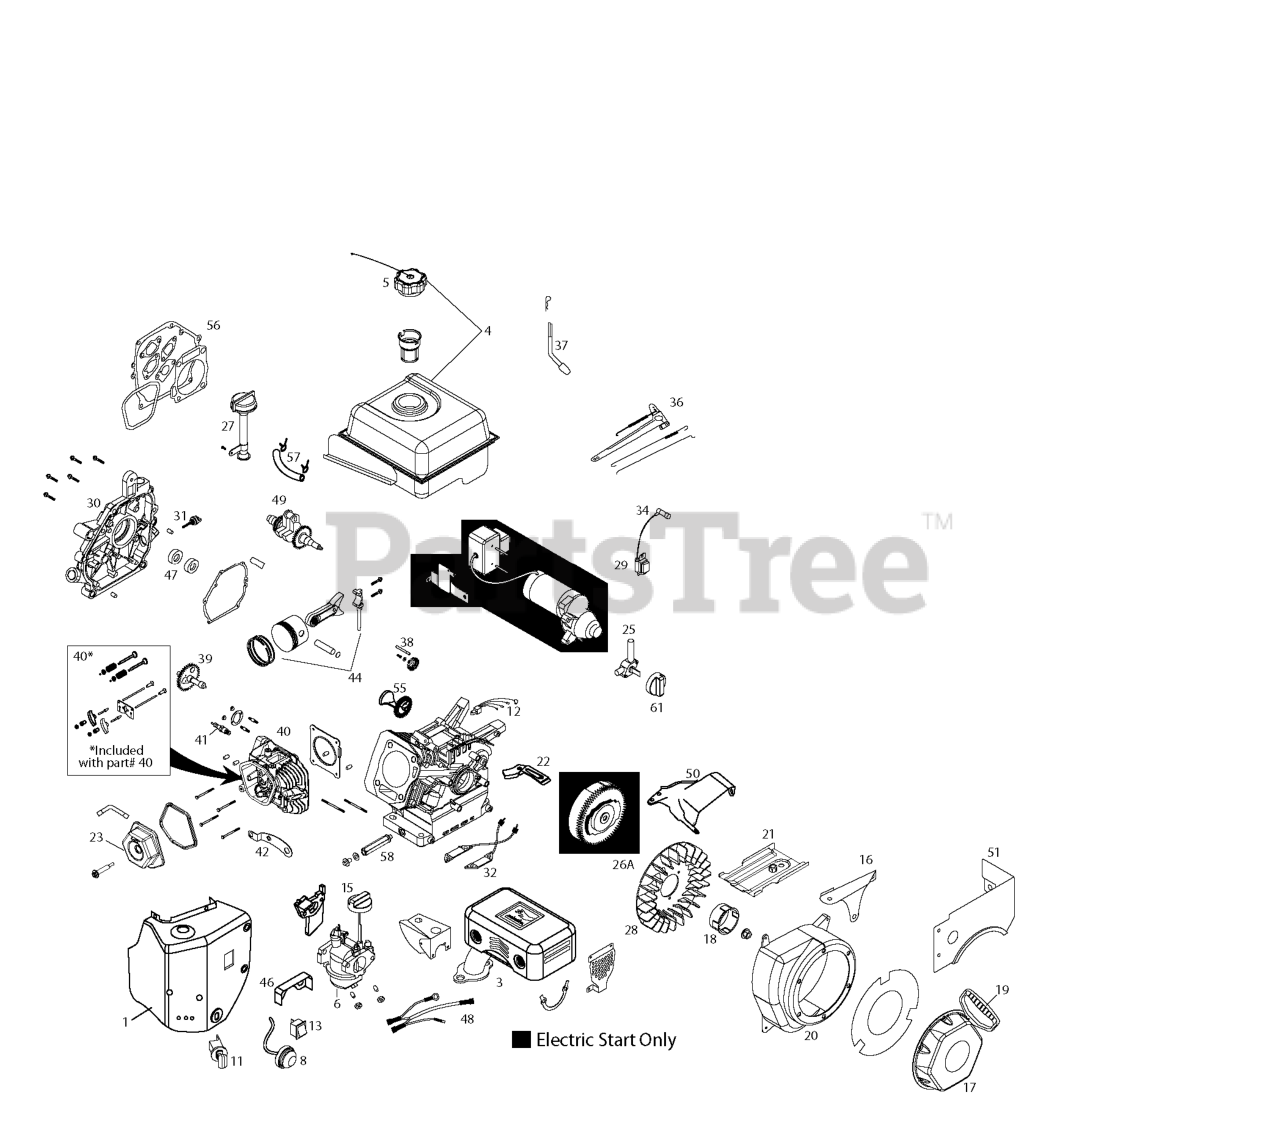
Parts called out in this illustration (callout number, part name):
1	HEATER.BOX.ASSY-SNW(SKSN4100)
3	MUFFLER.ASSY.SNOW(SKSN4200)
4	FUEL.TANK.ASSY.SNOW(SKSN4300)
5	FUEL.TANK.CAP.SNOW(SKSN4301)
6	CARBURETOR.ASSY.SNOW(SKSN4302)
8	PRIMER.BULB.ASSY(SKSN4304)
10	ELEC.START.ASSY.SNOW(SKSN4400)
11	KEY.SWITCH.ASSY.SNOW(SKSN4401)
12	CDI.BOX.ASSY.SNOW(SKSN4404)
13	ON/OFF.SWITCH.SNOW(SKSN4403)
15	CHOKE.KNOW.SNOW(SKSN4500)
16	CHUTE.LOWER.BAGGER.30"(2 2 BR)
17	RECOIL.START.ASSY.SNW(SKSN4600
18	STARTER.CUP.SML.SNOW(SKSN4601)
19	STARTER.GRIP.SNOW(SKSN4603.1)
20	BLOWER.HSG.ASSY.ELEC(SKSN4602
21	SHIELD.CYLINDER.SNOW(SK4141010
22	SHIELD.U/FYWHL.CHARG(SKSN4604)
23	VALVE.COVER.LCT.414CC.
25	FUEL.PETCOCK.SNOW(SKSN4900)
26	FLYWHEEL.ASSY.ELEC.START
26A	FLYWHEEL.ASSY.MAN.START
27	HIGHOIL.FILL.ASSY.KIT(SKSN4911
28	FLYWHEEL.FAN(SK4144000)
29	IGNITION.COIL.ASSY
30	CRANKCASE.CVR.ASSY(SK4143600)
31	NONREMVABLE.OIL.PLUG(SK4143715
32	CHARGING.COIL.AC/DC(SK4141710)
33	ELECTRIC.START.BRKT(SKSN4405)
34	SPARK.PLUG.BOOT
36	GOVERNOR.ARM.ASSY(SKSN4502)
37	GOVERNOR.SHAFT(SK4143100)
38	GOVERNOR.GEAR.ASSY(SK4142900)
39	CAMSHAFT(SK4141600)
40	CYL.HEAD.ASSY.45 DEG.NON-GEN
41	SPARK.PLUG(SK2911550)
42	CDI.BOX.BRKT.SNOW(SKSN4402)
44	PISTON.AND.ROD.ASSY(SK4141400)
46	SHIELD.VAPOR(SKSN4606)
47	OIL SEAL KIT NON-GENERATOR
48	WIRE.HARNESS(SKSN4406)
49	CRANKSHAFT.KEYED
50	RP TOP SHIELD
51	SKIRT FUEL TANK
55	COUNTER WEIGHT KIT
56	KIT.ENGINE GASKET.LCT.414CC
57	FUEL HOSE KIT
58	EXTENDED OIL DRAIN TUBE
61	FUEL KNOB-SNOW
